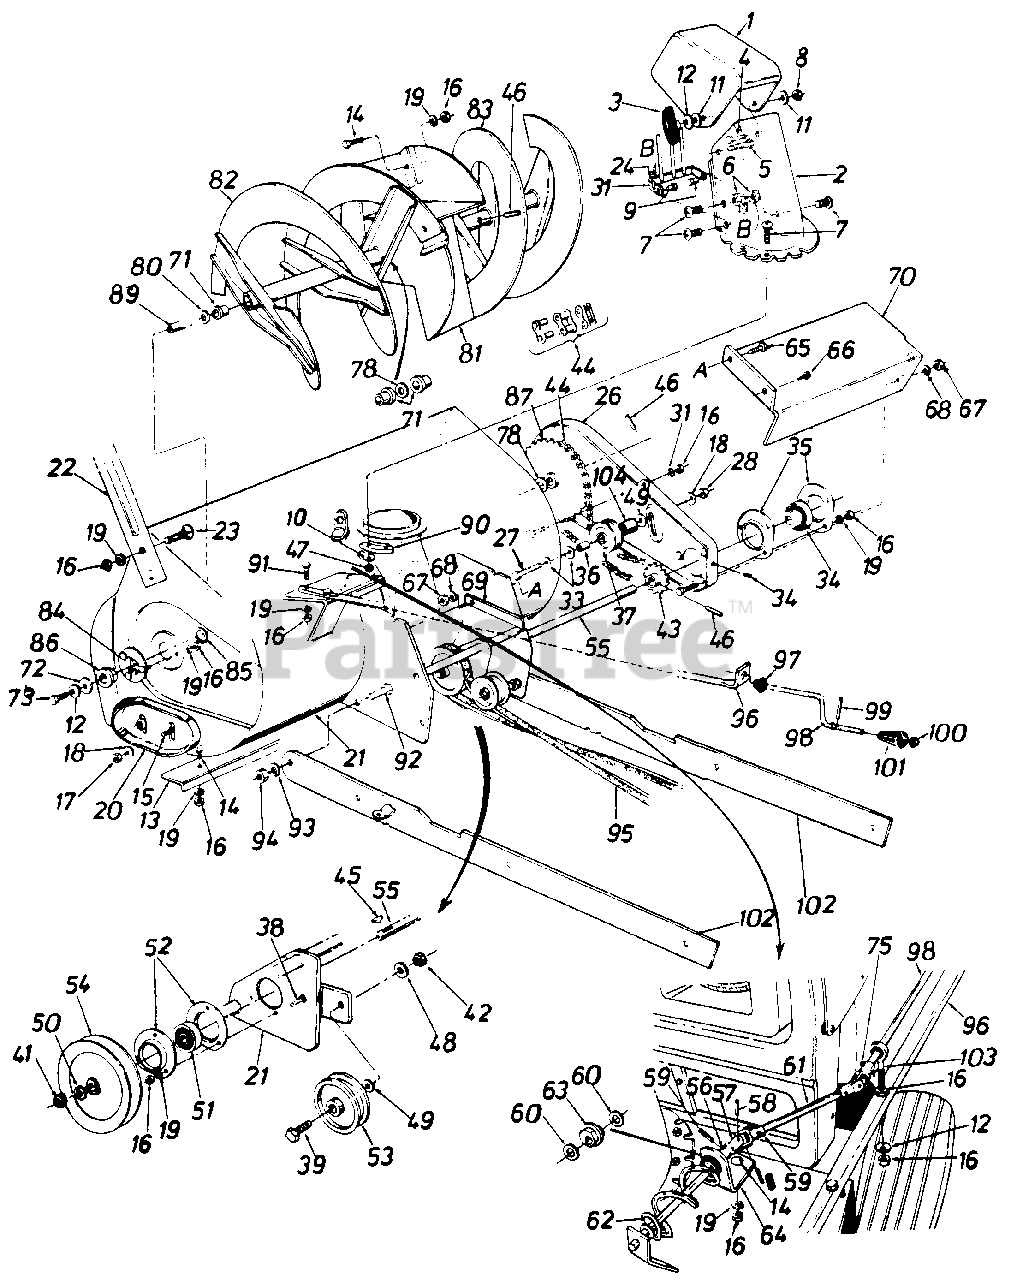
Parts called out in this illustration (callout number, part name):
1	Upper Chute
2	Lower Chute
3	Knob Handle Ass'y.
4	Truss Mach. Scr. 5/16-18 x .75" Lg.
5	Carriage Bolt 5/16-18 x 1.0"
6	Hex Cent. L-Nut 5/16-18 Thd.
7	Truss Mach. Scr. 1/4-20 x .75" Lg.
8	Hex Cent. L-Nut 5/16-18 Thd.
9	Shld. Nut 1/4-20 Thd.
10	Fl.-Wash. 1/4" I.D.
11	Fl.-Wash. .344" I.D. x 1.125"
12	Bell. Wash. .345" I.D. x .88"
14	Carriage Bolt 5/16-18 x .62"
15	Carriage Bolt 3/8-16 x .62"
16	Hex Nut 5/16-18 Thd.
17	Hex Jam Nut 3/8-16 Thd.
18	Bell. Wash. .40 I.D. x .88"
19	L.-Wash. 5/16" I.D.
20	Slide Shoe
21	Spiral Hsg. Ass'y.-36"
22	Guide B ade
23	Carriage Bolt 5/16-18 x .62"
24	Extension Spring
26	Chain Guard Ass'y.
27	Hex Bolt 3/8-16 x 2.00 4.
28	Hex Inst.-Nut 3/8-16 Thd.
33	Fl.-Wash. .385" I.D. x .87" O.D.
34	Ball Brg. .75" I.D.
35	Flangette
36	Spacer .375" I.D. x .60" O.D.
37	Fl.-ldlere w/Flangas 1.875
38	Hex Sems Bolt 5/18 x .75" 4.
39	Hex Bolt 3/8-1tS x 1.75" 4.
41	Hex Jam Nut 3/410 Thd.
42	Hex Jam Nut 3/8-16 Thd.
43	Sprockat Ass'y.-14 Teth
44	#420 Chain x 1/2" Pitch- 0 77 Links
45	#61 Hi-Pro-Koy 3/16 x 5/8"
46	Spring Pln Spir. 5/16" Dia. x 1.75" 4.
47	Hex L-Nut 1/4-20 Thd.
48	L.-Wash. 3/8" I.D.
49	fl.-Wash. .4013" I.D. x 1.25"
50	Spring L.-Wash. 3/4" I.D.
51	Self-Aligning Brg.
52	Flangette
53	Ider Pulley
54	5/8 V-Pulley .75" I.D. x 6"
55	Drive Shaft Ass'y.
56	Joint Brkt. Ass'y.
58	Oval Head Rivet
59	Spiral Pin 1/8" Dia.
60	Fl.-Wash. .385" I.D. x .62"
61	Chute Crank Ext. Rod
62	Chute Crank Ass'y. R.H.
63	Plastic Bushing .380" I.D.
64	Chute Crank Brkt.
65	Hex Bolt 1/4-20 x .62" Lg.
66	Hex Wash. S-Tap Scr. 1/4-20 x .50" 4
67	Hex Nut 1/4-20 Thd.
68	L.-Wash. 1/4" I.D.
70	D-ive Shaft Cover
71	Plastic Bushing
72	Washer .39" I.D. x 1.75" O.D.
73	Hex Bolt 5/16-18 x .88" Spec.
75	Cotter Pin 3/32" Dia.
78	Fl.-Wash. 1.03" I.D. x 1.62"
80	Fl.-Wash. 1.0" x 1.75"
85	Snap Ring for 1.50" Shaft
86	Flange Brg. w/flats 1.00" I.D.
87	Sprocket Hub Ass'y. 40 Teeth
90	Chute Flange Keeper
91	Hex Bolt 5/16-18 x 1.5" 4.
92	Hex Bolt 1/2-13 x 1.25" 4.
93	L.-Wash. 1/2" I.D.
94	Hex Nut 1/2"-13 Thd.
95	"V"-Belt
98	Chute Crank 34.5" 4.
99	Roll Pin .12 Dia. x .63
100	Push Nut 3/8" Rod
102	Linkage Arm
103	Eye Bolt 5/16-18 x 3.0" lg.
104	Idler Spacer
